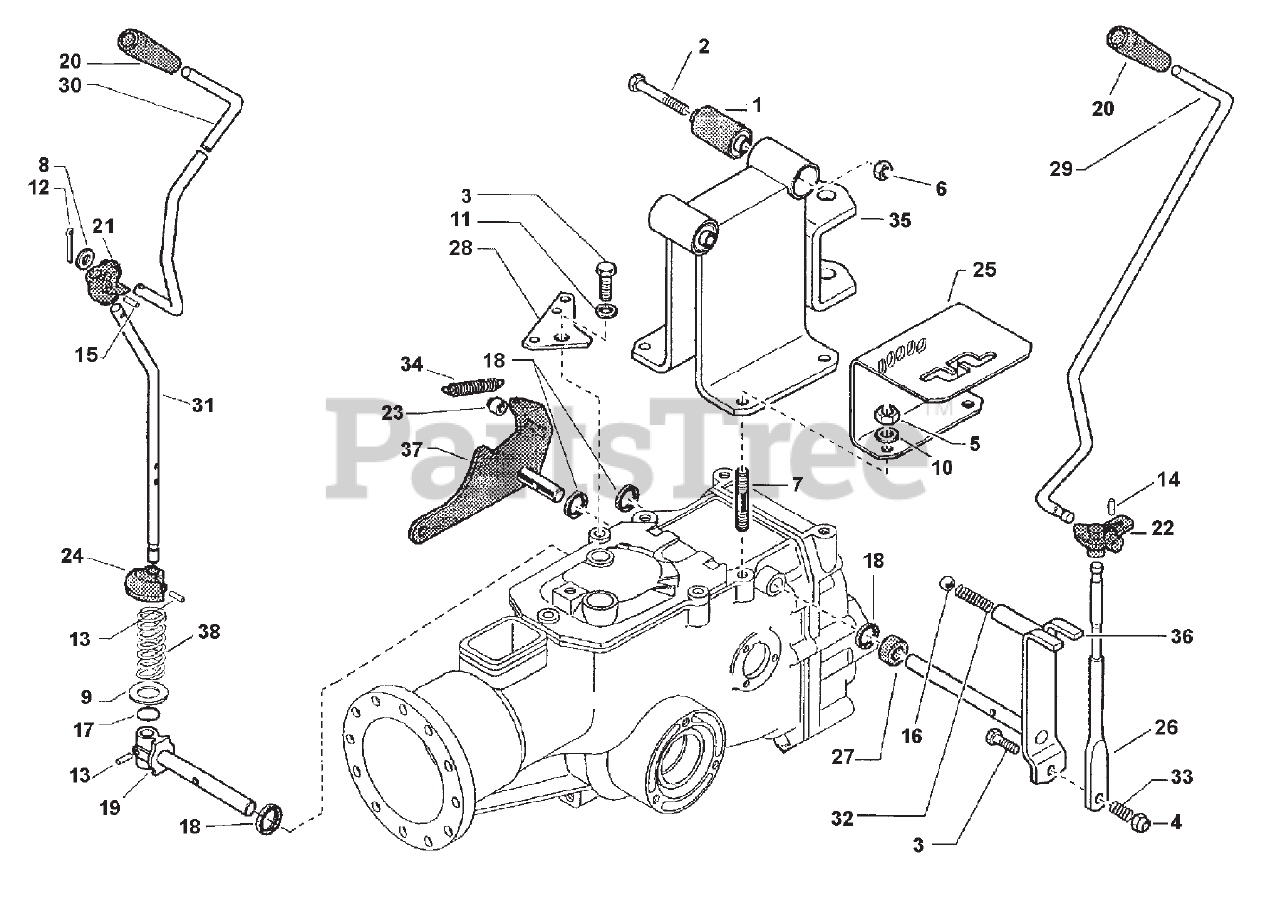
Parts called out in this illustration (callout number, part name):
1	SILENT BLOCK
2	CAP SCREW, M10X75
3	CAP SCREW, M8X30
4	LOCK NUT, M8
5	LOCK NUT, M8 DEFORMED
6	LOCK NUT, M10
7	STUD, M8X35X14X20
8	WASHER, FLAT M10.5X8
9	WASHER, FLAT M13
10	WASHER, SUPER M8
11	WASHER, LOCK M8.4 DIN13
12	PIN, COTTER A 2X15
13	PIN, SPLIT 4X20 SPIROL
14	PIN, SPLIT 3X22 SPIROL
15	PIN, SPLIT 4X24 SPIROL
16	BALL 15/32
17	O-RING
18	OIL SEAL M14X22X4
19	PTO SHAFT
21	PTO ARTICULATOR
22	SPEED ARTICULATOR
23	PIN, PTO LOCKOUT
24	PTO LOCKOUT
25	GEAR SELECTOR 3+2
26	LEVER, SPEED CONTROL
27	SPACER
28	REVERSE BRACKET
29	ROD, SPEED
30	ROD, PTO
31	SHIFT ARM, PTO
32	SPRING
33	SPRING
34	SPRING
35	SUPPORT, HANDLEBAR
36	GEAR LEVER 3+2
37	LEVER, PTO LOCKOUT
